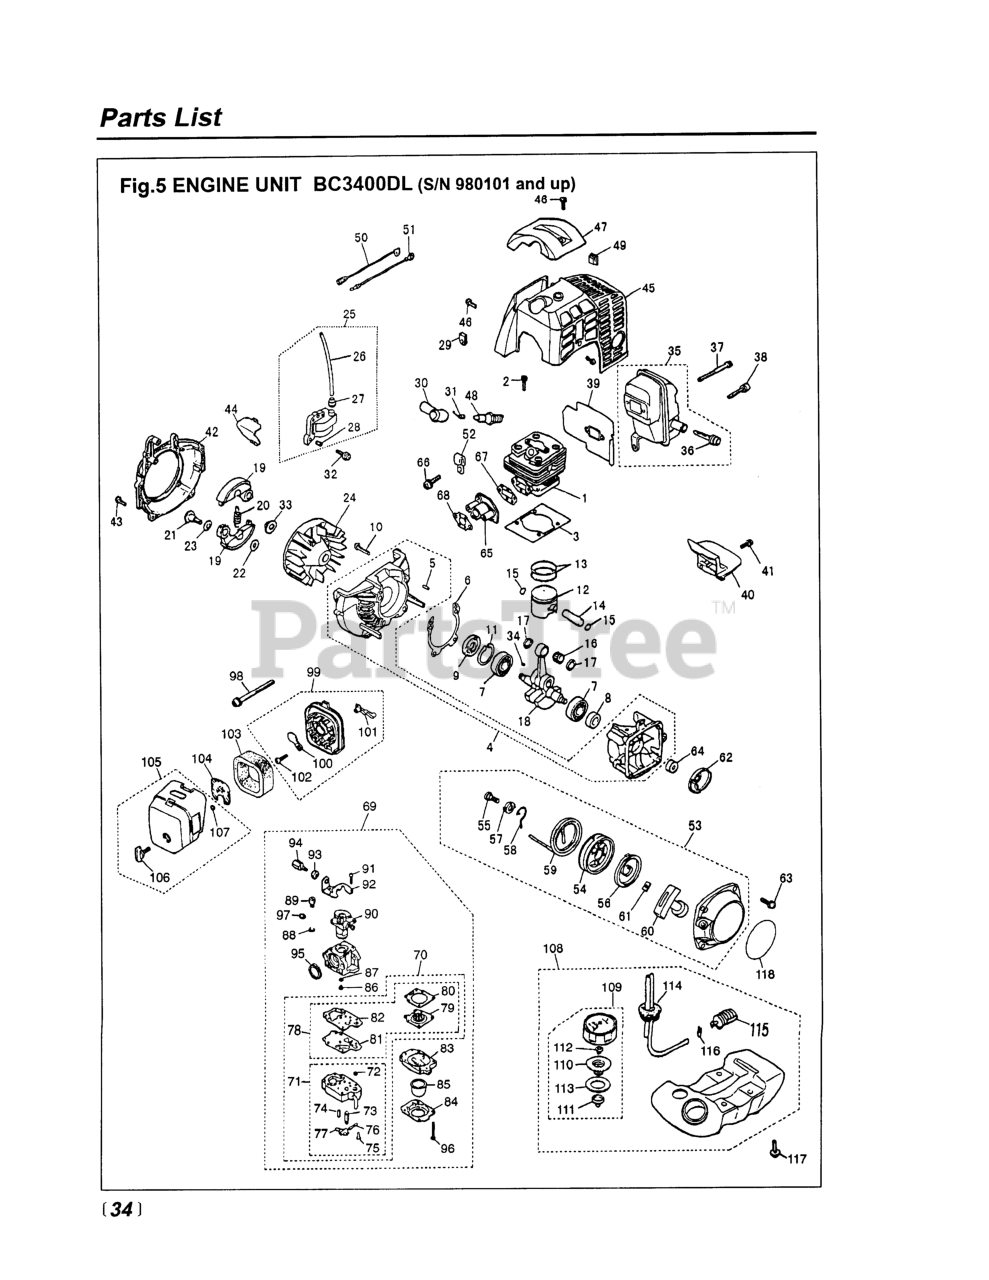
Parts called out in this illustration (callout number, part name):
1	CYLINDER
2	BOLT M5 x 20 (RPLS -12280)
3	GASKET, BASE
4	CRANKCASE COMPL (USE -21101)
5	PIN
6	GASKET
8	SEAL
9	SEAL, OIL (RPLS 1200-21220)
10	BOLT, M5 X 30
11	RING, SNAP, M32 x 1.2
12	PISTON
13	RING, PISTON
14	PIN, PISTON
15	RING, SNAP
16	BEARING
17	WASHER
18	CRANKSHAFT COMPL
19	SHOE, CLUTCH (RPLS -51110)
20	SPRING
21	SCREW
22	WASHER
23	WASHER (RPLS. -51240)
24	ROTOR
25	COIL ASSEMBLY
29	GROMMET
31	SPRING
32	BOLT, M4 x 22
34	KEY
35	MUFFLER ASSEMBLY
36	ARRESTER (RPLS 5850-15140)
37	BOLT, M5 x 60
38	BOLT (REPLACES 01252-30514)
40	PLATE (USE-15221)
41	SCREW,M5 X 14 (RPLS 1400-15510
43	BOLT M5 x 20 (RPLS -12280)
45	COVER
46	SCREW M5 x 12
47	GUARD
50	CORD
51	CORD, EARTH
52	CLAMP
53	RECOIL ASSEMBLY
54	REEL
55	SCREW
56	SPRING, SPIRAL
57	COLLAR
58	ARM
59	ROPE (USE 4810-75160)
60	KNOB
61	PLATE, STOPPER
62	PULLEY
63	SCREW, M6 x 14
66	SCREW, M5 X 20 (USE 5516-85510
67	GASKET, INSULATOR
68	GASKET, CARBURETOR
69	CARBURETOR ASSEMBLY
71	BODY, PUMP
72	SCREEN
73	VALVE, INLET
75	SCREW
76	PIN
77	LEVER
79	DIAPHRAGM
80	GASKET, DIAPHRAGM
81	DIAPHRAGM, PUMP
82	GASKET, PUMP
83	BODY, PURGE
84	COVER, PUMP
85	PUMP, PRIMING
86	JET
87	RING, O
88	RING
89	SWIVEL
90	VALVE ASSY
91	SCREW
93	NUT, CABLE ADJUSTER
94	SCREW, CABLE ADJUSTER
95	RING, PACKING
96	SCREW
97	WASHER
99	BODY ASSEMBLY
100	PLATE, CHOKE
101	LEVER, CHOKE
102	SCREW (REPLACES 50030272)
103	ELEMENT
104	SCREEN
106	KNOB (RPLS -82220)
107	RING
110	HOLDER (USE -85300)
111	HOLDER, CAP
112	VALVE (NLA WHEN OUT)
113	PACKING
114	PIPE COMPLETE
115	FILTER ASSY
116	CLIP (REPLACES 2841-31280)
117	SCREW, M5 X 22
118	LABEL, RECOIL
